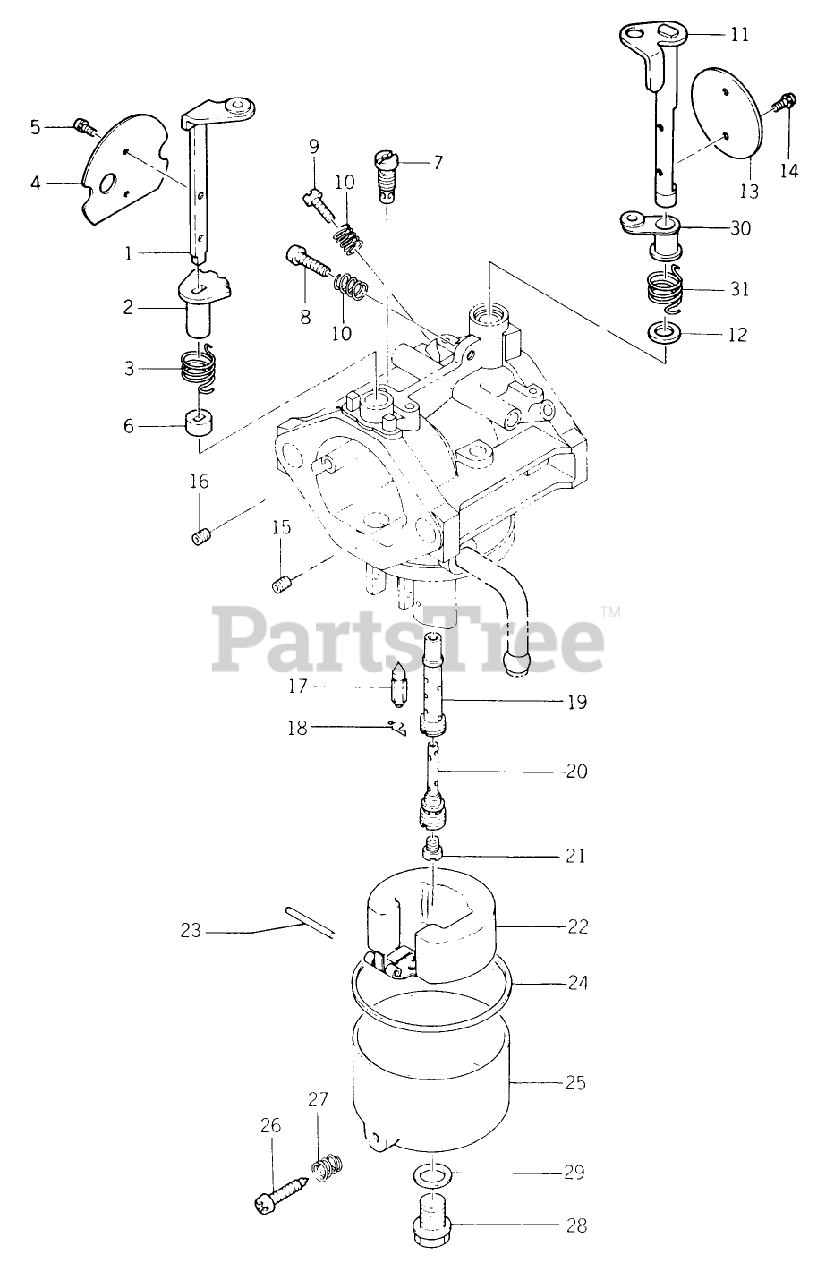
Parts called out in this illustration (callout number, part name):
1	?SHAFT, choke
2	?COLLAR
3	?SPRING
4	?VALVE, choke
7	?JET, pilot (No.50)
8	?SCREW (4x12)
9	?SCREW, adjuster
11	?SHAFT, throttle
13	?VALVE, throttle (No.110)
15	Jet-Air, #1.7
16	?JET, pilot air (No.1.1)
17	Valve-Float
19	?NOZZLE, main (No.12C)
20	?PIPE, bleed
21	?JET, main (=97.5)
23	PIN, float
25	Float Chamber Assy (includes items 18 19).
30	?COLLAR
31	?SPRING
